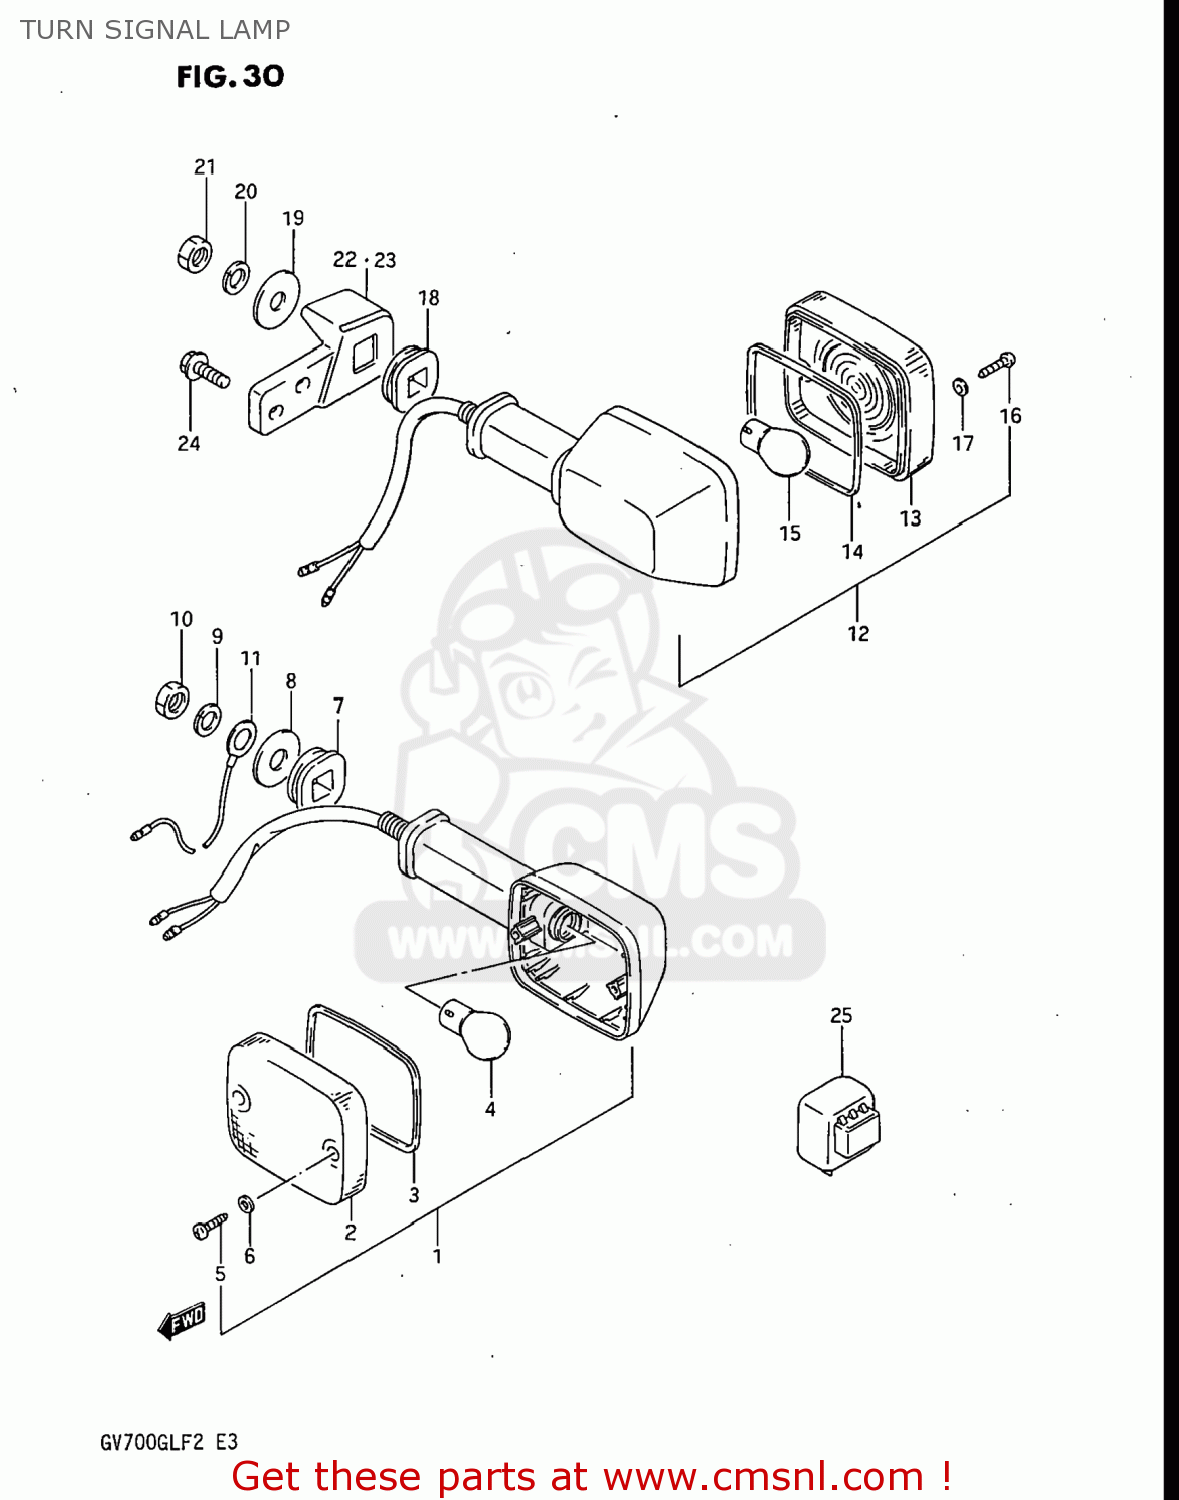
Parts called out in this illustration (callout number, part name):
1	LAMP ASSY,FR TURN SIGNAL
2	LENS
3	GASKET (NAS)
4	BULB(12V23W)
5	SCREW
6	GASKET (NAS)
7	CUSHION
8	WASHER (10.5X30X2.3)
9	LOCK WASHER
10	NUT
11	WIRE
12	LAMP ASSEMBLY,REAR TURN SIGNAL
13	LENS
14	GASKET (NAS)
15	BULB(12V23W,STANLEY,A4577A)
16	SCREW
17	GASKET (NAS)
18	CUSHION
19	WASHER (10.5X30X2.3)
20	LOCK WASHER
21	NUT
22	BRACKET,RR TURNSIGNAL LAMP,R
23	BRACKET,RR TURNSIGNAL LAMP,L
24	BOLT
25	RELAY ASSEMBLY,TURN SIGNAL
